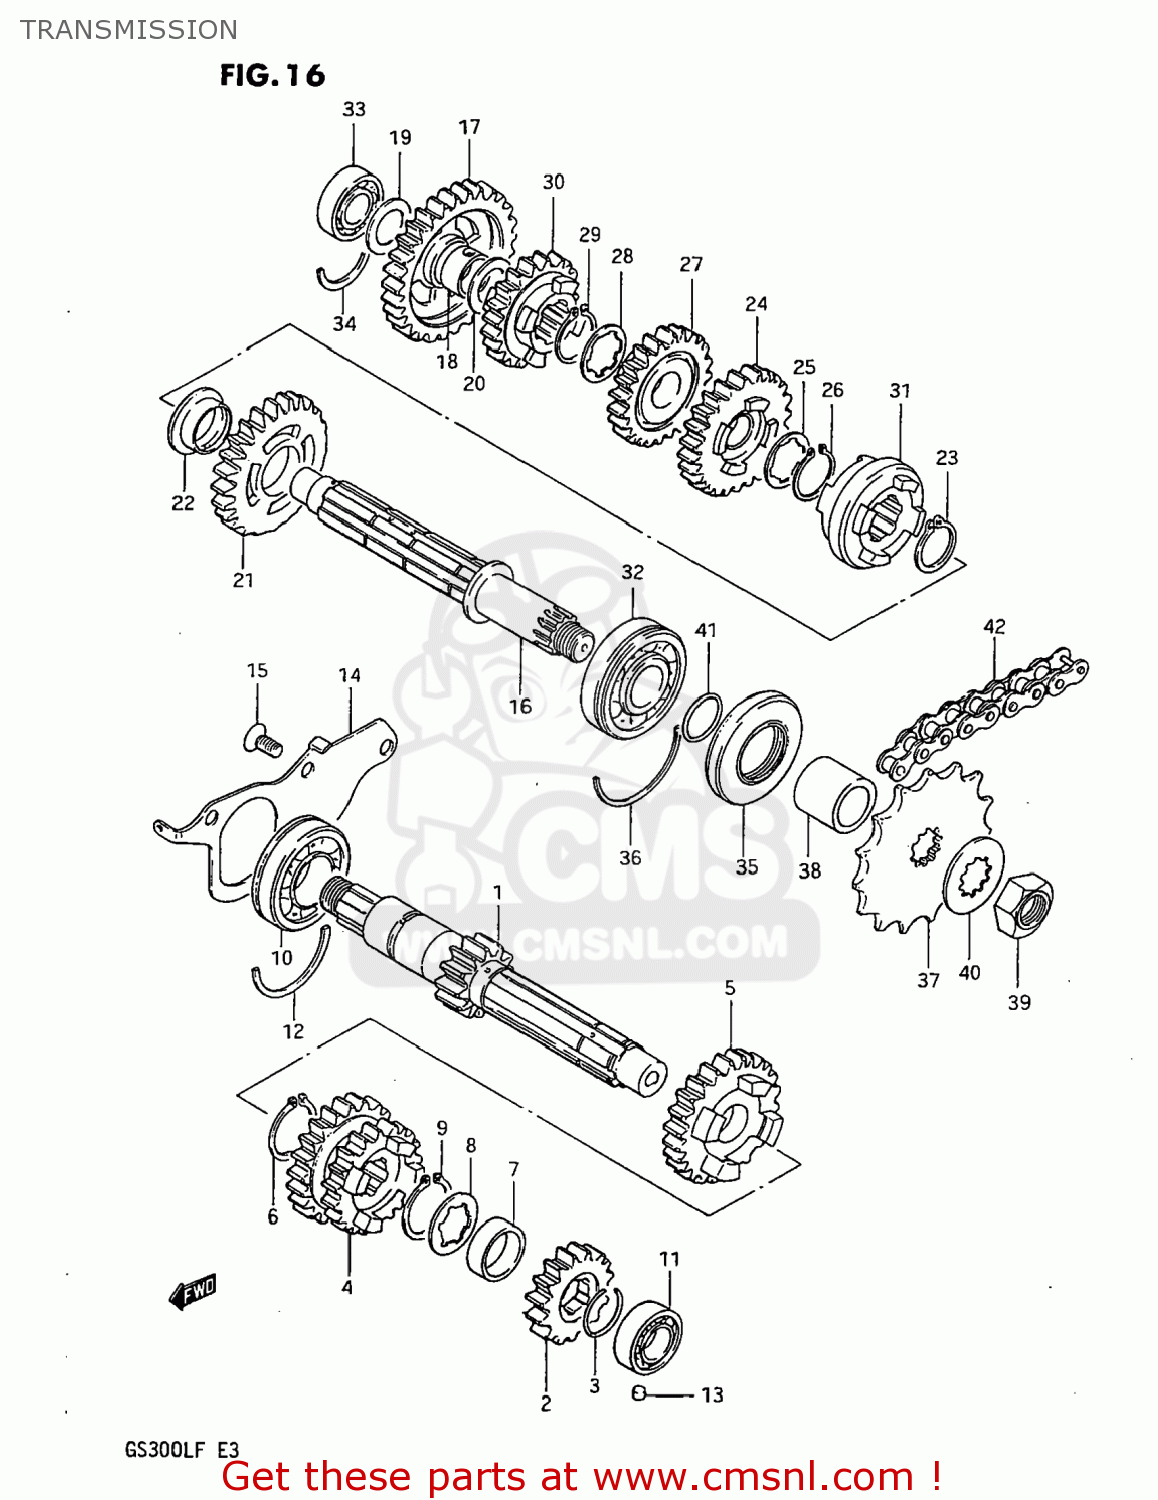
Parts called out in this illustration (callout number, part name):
1	SHAFT,COUNTER
2	GEAR,SECOND DRIVE
3	CIRCLIP
4	GEAR,THIRD/FOURTH DRIVE
5	GEAR,FIFTH DRIVE
6	CIRCLIP
7	SPACER
8	WASHER,LOCK
9	CIRCLIP
10	BEARING
11	ROLLER BEARING (17X31X1
12	C RING
13	PIN
14	RETAINER,BEARING
15	SCREW
16	SHAFT,DRIVE
17	GEAR,FIRST DRIVEN
18	BUSHING
19	WASHER,THRUST
20	WASHER,THRUST
21	GEAR,SECOND DRIVEN
22	BUSH
23	CIRCLIP
24	GEAR,THIRD DRIVEN
25	WASHER,LOCK
26	CIRCLIP
27	GEAR,FOURTH DRIVEN
28	WASHER,LOCK
29	CIRCLIP
30	GEAR,FIFTH DRIVEN
32	BEARING
33	BEARING
34	C RING
35	SEAL,OIL(28X52X11.5)
36	C RING
37	SPROCKET,ENGINE(NT:15)
38	SPACER (20X28X25.2)
39	NUT
40	WASHER,LOCK
41	O RING(D:1,ID:19.5)
42	CHAIN,DRIVE #520UB-10
